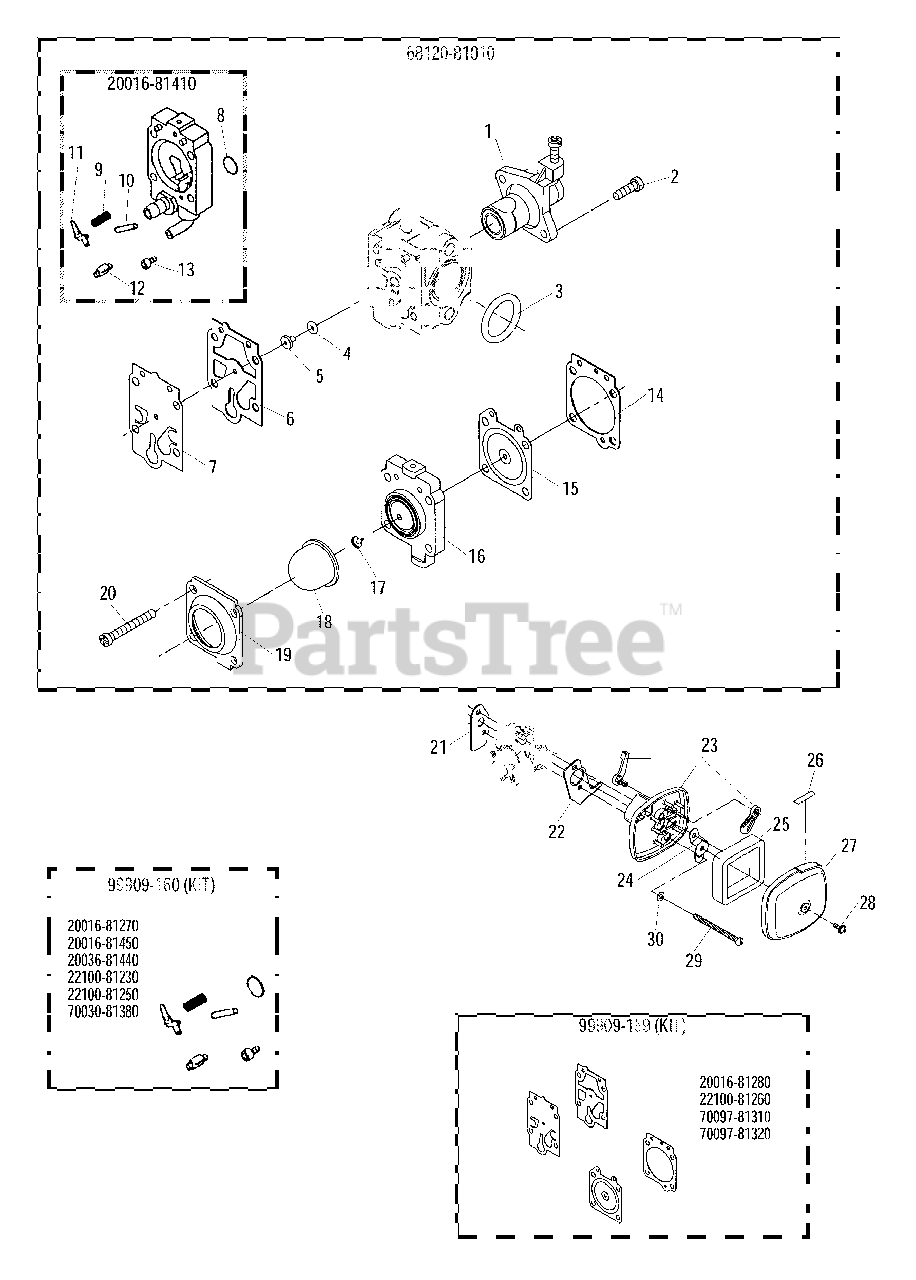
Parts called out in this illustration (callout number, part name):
1	THROTTLE VALVE ASSY
2	SCREW
3	O-RING - 15
4	O-RING
5	JET, MAIN - 1000M #40
6	GASKET, PUMP
7	DIAPHRAGM, PUMP
8	STRAINER
9	SPRING, METERING LEVER
10	PIN, METERING LEVER
11	LEVER, METERING
12	VALVE, INLET NEEDLE
13	SCREW, METERING LEVER PIN
14	GASKET, METERING
15	DIAPHRAGM, METERING
16	BASE, PURGE
17	VALVE, CHECK
18	BULB, PURGE
19	RETAINER, PURGE BULB
20	SCREW, PUMP COVER
21	GASKET
22	HOLDER, CABLE
23	CASE, AIR FILTER
24	PLATE, PREVENT
25	FILTER, AIR
26	LABEL - CHOKE
27	COVER, AIR FILTER
28	SCREW
29	SCREW - 5X60
30	WASHER - 5
20016-81410	PUMP BODY ASSY
68120-81010	CARBURETOR
99909-159	DIAPHRAGM/GASKET KIT
99909-160	REPAIR KIT
